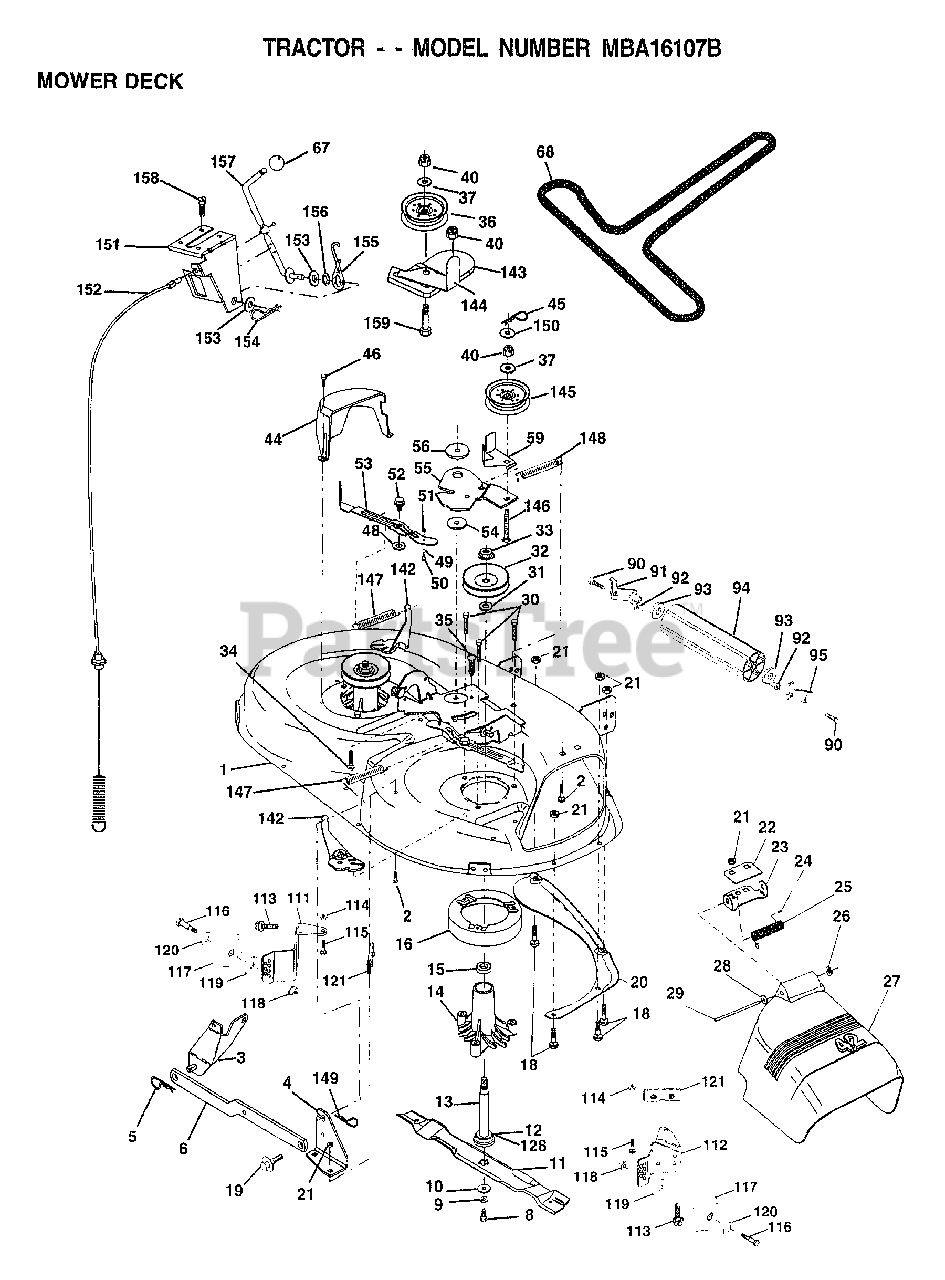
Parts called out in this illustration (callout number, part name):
1	MOWER DECK ASSY
2	BOLT
3	BRKT ASM SWAY BAR
4	BRACKET DECK
8	BLADE BOLT
10	WASHER.HARD.BLADE
11	"BLADE.42"" HIPERF"
12	BEARING.BALL
14	HSG ASM MANDREL
15	BEARING
16	STRIPPER RND MWR
18	BOLT
19	BOLT SHD 5/16-18
20	BAFFLE VORTEX 42
22	STIFFENER BRKT
23	DEFLECTOR BRKT
24	CAP-SLEEVE LT
25	SPRING TORSION
26	NUT PUSH M
27	SHIELD DEFLECTOR 42''
28	WASHER
29	HINGE ROD
30	"SCREW-THD ROLL,WA"
31	WASHER
32	PULLEY.MANDREL.42
34	BOLT
35	XMAS TREE FASTNER
36	FLAT IDLER PULLEY
37	WASHER
44	GUARD MAND LH BLK
45	RETAINER M
46	SCREW.1/4-20X5/8
48	HARD SMALL WASHER
49	ROLLER ASM-CAM
50	SHOULDER BOLT
51	LOCKNUT
52	BOLT.SHLD.5/16-18
53	BRAKE PAD ARM ASM
54	HARDENED WASHER
55	ARM-IDLER
56	SPACER.RETAINER.MOWER
59	GUARD IDLER TUV
67	KNOB T(3/8 HOLE)
68	BELT-V.SEC.46.KEL
90	BOLT
92	NUT
93	WASHER
111	BRACKET.GWHL.LH.
112	BRACKET.GWHL.RH.
113	SCREW
116	BOLT M
117	WHEEL.GAGE.BLK.PL
118	LOCKNUT
119	WASHER
120	WASHER
121	BRACKET.EXTRD.GWL
128	WASHER.FELT.
142	ARM SPRING BRAKE MOWER
143	BRACKET ARM IDLER
144	KEEPER BELT CLUTCH CABLE
145	PULLEY IDLER FLAT
146	BOLT
147	SPRING EXTENSION
148	SPRING RETURN IDLER
149	RETAINER SPRING
150	WASHER PM
151	BRKT CLUTCH CABLE
152	"CABLE.CLUTCH.42"""
153	WASHER FLAT
154	SPRING RETAINER
155	SPRING RETENTION LVR CLUTCH CAB
156	SPACER
157	ROD.CLUTCH.CABLE.3/8
158	SCREW LT
159	BOLT
